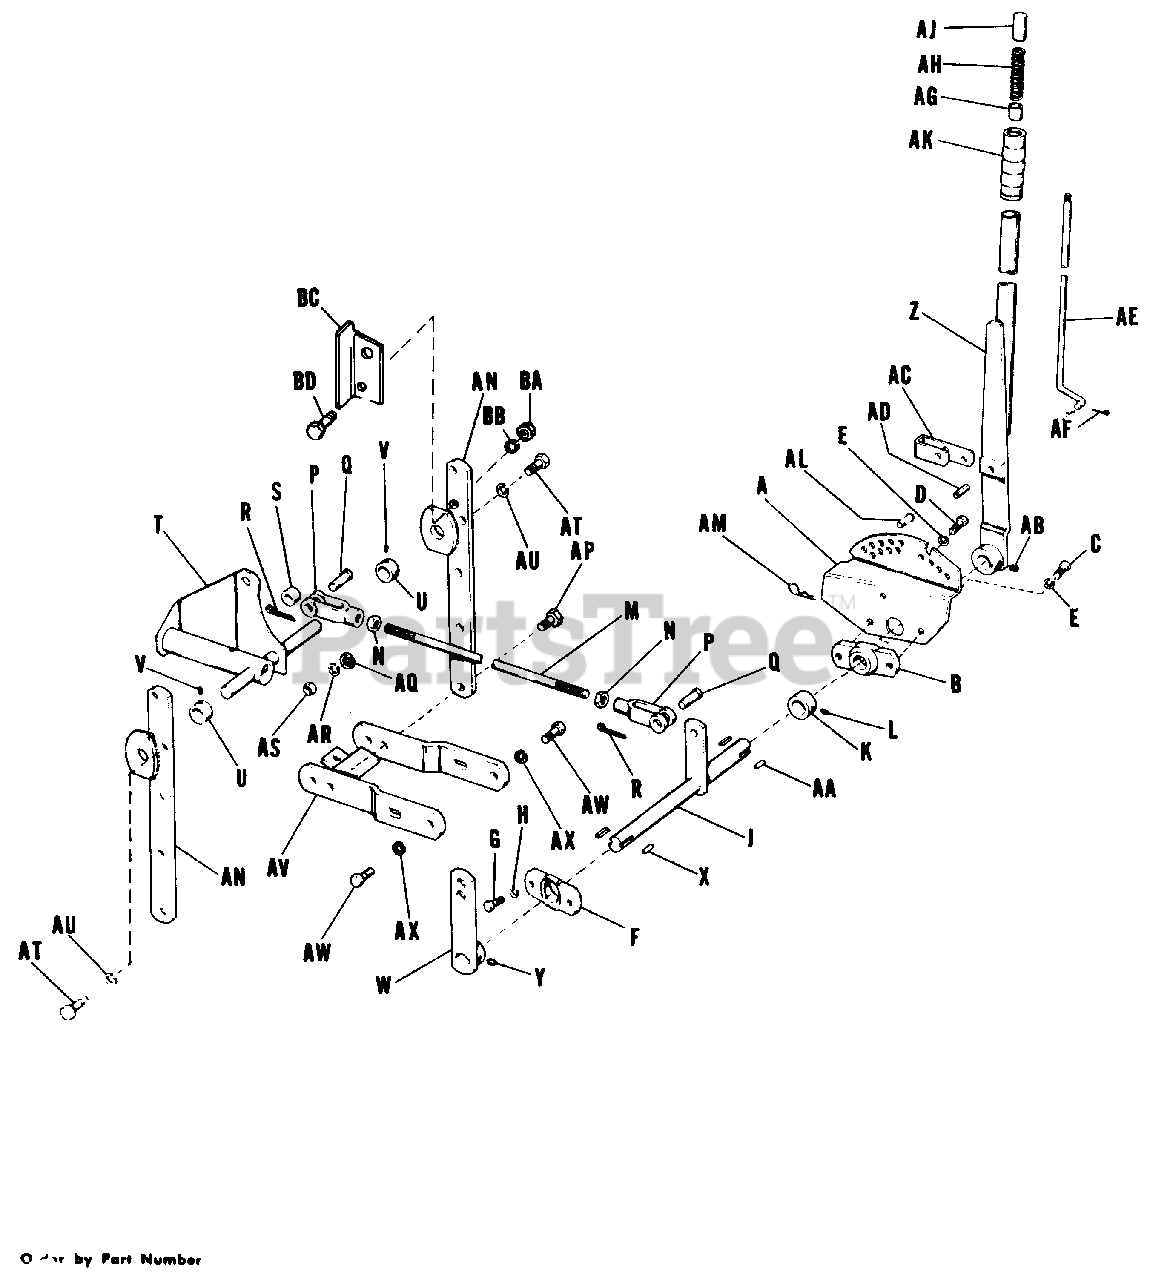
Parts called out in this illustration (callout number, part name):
A	Quadrant, Lift Lever
B	Bearing, Lift Lever
C	Screw, Cap, Hex., 3/8"-16 N.C. x 7/8" lg.
D	Screw, Cap, Hex., 3/8"-16 N.C. x 1-1/4" lg.
E	Washer, Lock, 3/8"
F	Bearing, Lift Lever
G	Screw, Cap, Hex., 3/8"-16 N.C. x 7/8" lg.
H	Washer, Lock, 3/8"
J	Shaft Assembly, Lift
K	Collar, Set
L	Screw, Set, Cup Point, Socket Head, 5/16"-18 N.C. x 5/16" lg.
M	Rod, Rear Lift
N	Nut, Hex., Full, 1/2"-20 N.C.
P	Yoke End, Adj.
Q	Pin, Yoke
R	Pin, Cotter, 1/8" x 1" lg.
T	Lift Assembly, Tiller
U	Collar, Set
V	Screw, Set, Cup Point, Socket Head, 5/16"-18 N.C. x 5/16" lg.
W	Lever Assembly, Front Lift
Y	Screw, Set, Cup Point, Socket Head, 5/16"-18 N.C. x 1/4" lg.
Z	Lever Assembly, Lift
AB	Screw, Set, Cup Point, Hollow Head, 5/16"-18 N.C. x 1/4" lg.
AC	Latch, Lift Lever
AD	Pin, Roll
AE	Rod, Latch
AF	Pin, Cotter, 3/32" x 3/4" lg.
AJ	Button, Thumb
AK	Grip, Handle
AM	Clip, Spring
AN	Arm Assembly
AP	Screw, Cap, Hex., 7/16"-14 N.C. x 1
AQ	Washer, Plain, 3/8"
AR	Washer, Lock, 3/8"
AS	Nut, Hex., Full, 7/16"
AT	Screw, Cap, Hex., 7/16"-14 N.C. x 1" lg.
AU	Washer, Lock, 7/16"
AV	Bar Assembly, Draw
AW	Screw, Cap, Hex., 7/16"-14 N.C. x 1" lg.
AX	Washer. Lock. 7/16"
BA	Nut Full Hex. 5/16"
BB	Washer, Lock 5/16
BC	Stop Seat
BD	Screw, Cap Hex. 5/16-18 N.C. x 7/8 lg.
